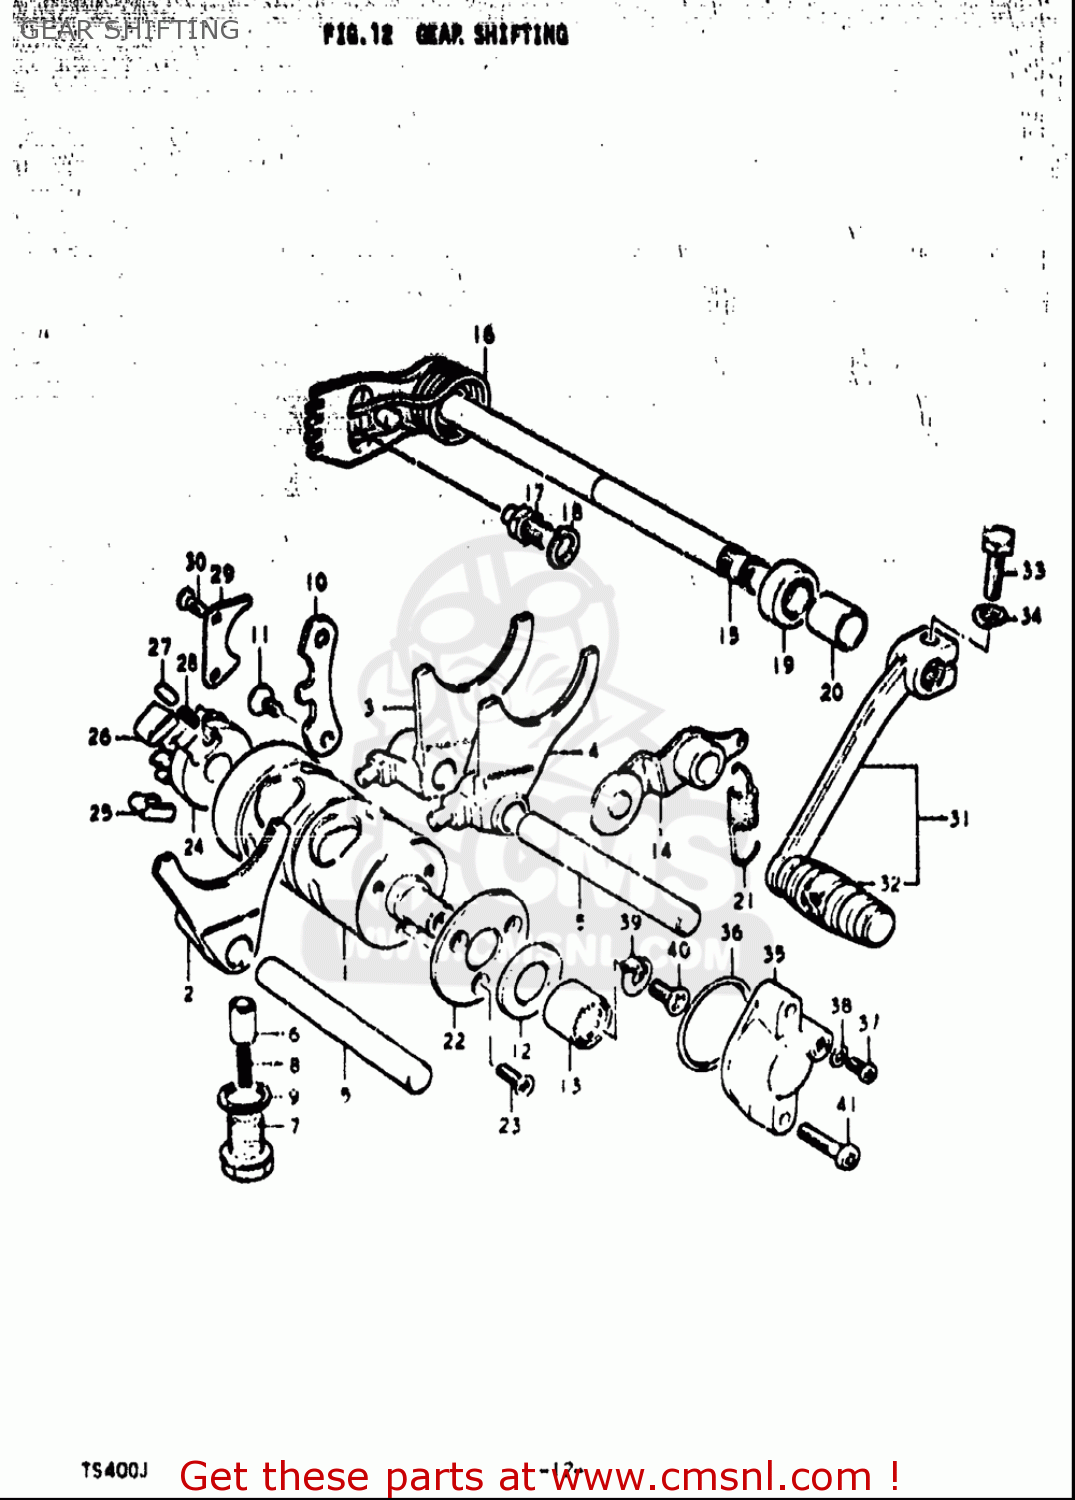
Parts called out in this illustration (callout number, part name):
5	SHAFT,GEAR SHIFT FORK
6	STOPPER,GEAR SHIFT CAM
7	HOUSING,GEAR SHIFT CAM STOPPER
8	SPRING
9	GASKET(14X19.2X2) (NAS)
11	SCREW
14	STOPPER,GEAR SHIFTING
16	SPRING
17	STOPPER,GEAR SHIFT ARM
18	WASHER,LOCK
19	SEAL,OIL (12X22X9)
20	CUSHION
21	SPRING
23	SCREW
25	PAWL,GEAR SHIFT NO.1
26	PAWL,GEAR SHIFT NO.2
27	PIN(5X8)
28	SPRING
30	SCREW
31	LEVER ASSY,GEAR SHIFT
32	RUBBER,GEAR SHIFT PEDAL
33	BOLT
34	WASHER,LOCK
35	BODY,GEAR SHIFT SWITCH
36	O RING(D:1.9,ID:27.7)
37	SCREW
38	WASHER
39	CONTACT,GEAR SHIFT SWITCH
40	SCREW
41	SCREW
